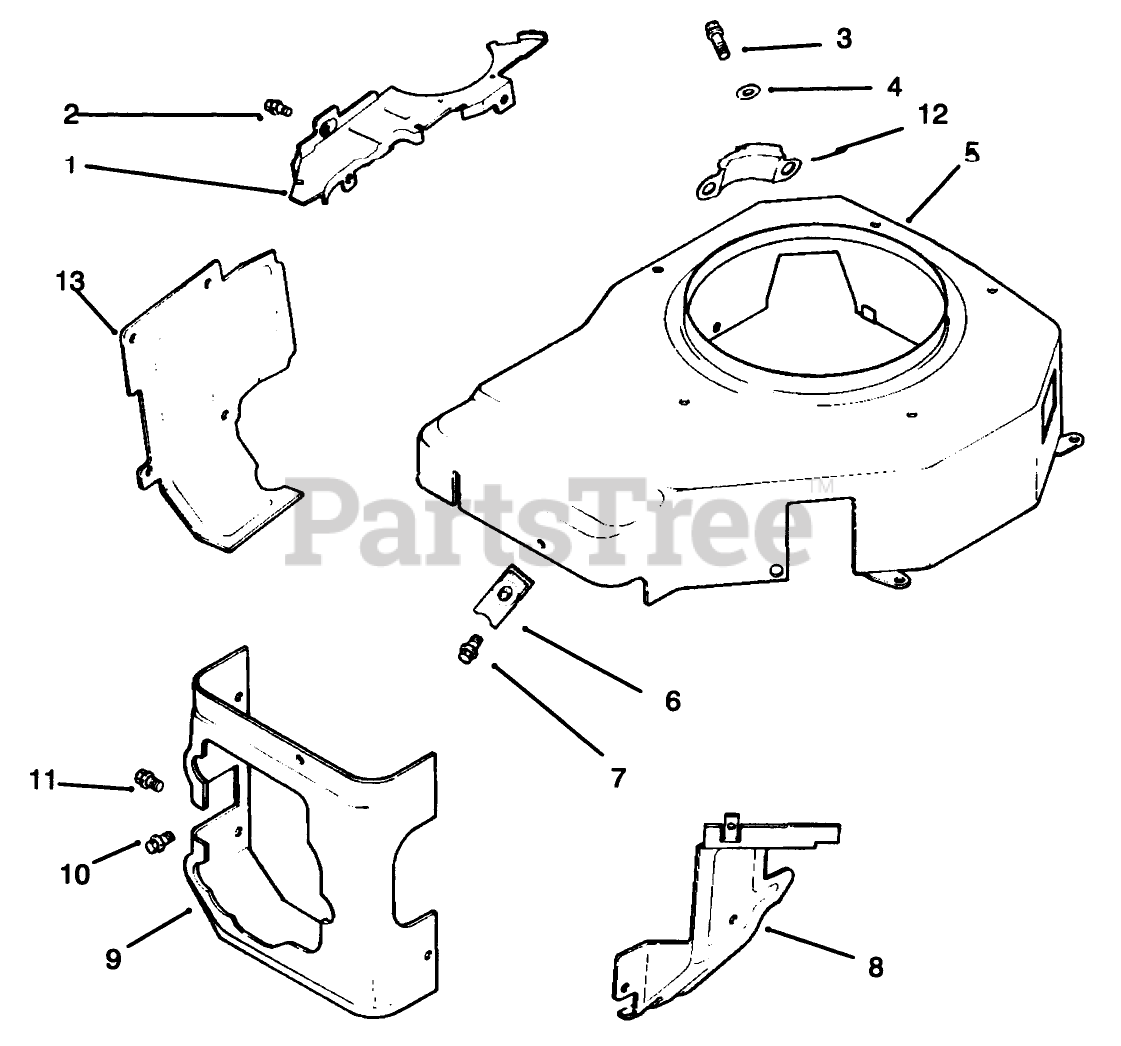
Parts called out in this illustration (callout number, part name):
1	Plate-Blower Housing (Only On: 72042,72043,72062,72063)
4	Washer
5	Housing-Blower
8	Baffle-Carburetor (Only On: 72042, 72043, 72062, 72063)
9	Baffle-Cylinder Head (Only On: 72042, 72063, 72062, 72043)
12	Cover-Pinion
13	Baffle-Cylinder Barrel (Only On: 72042, 72063, 72062, 72043)
